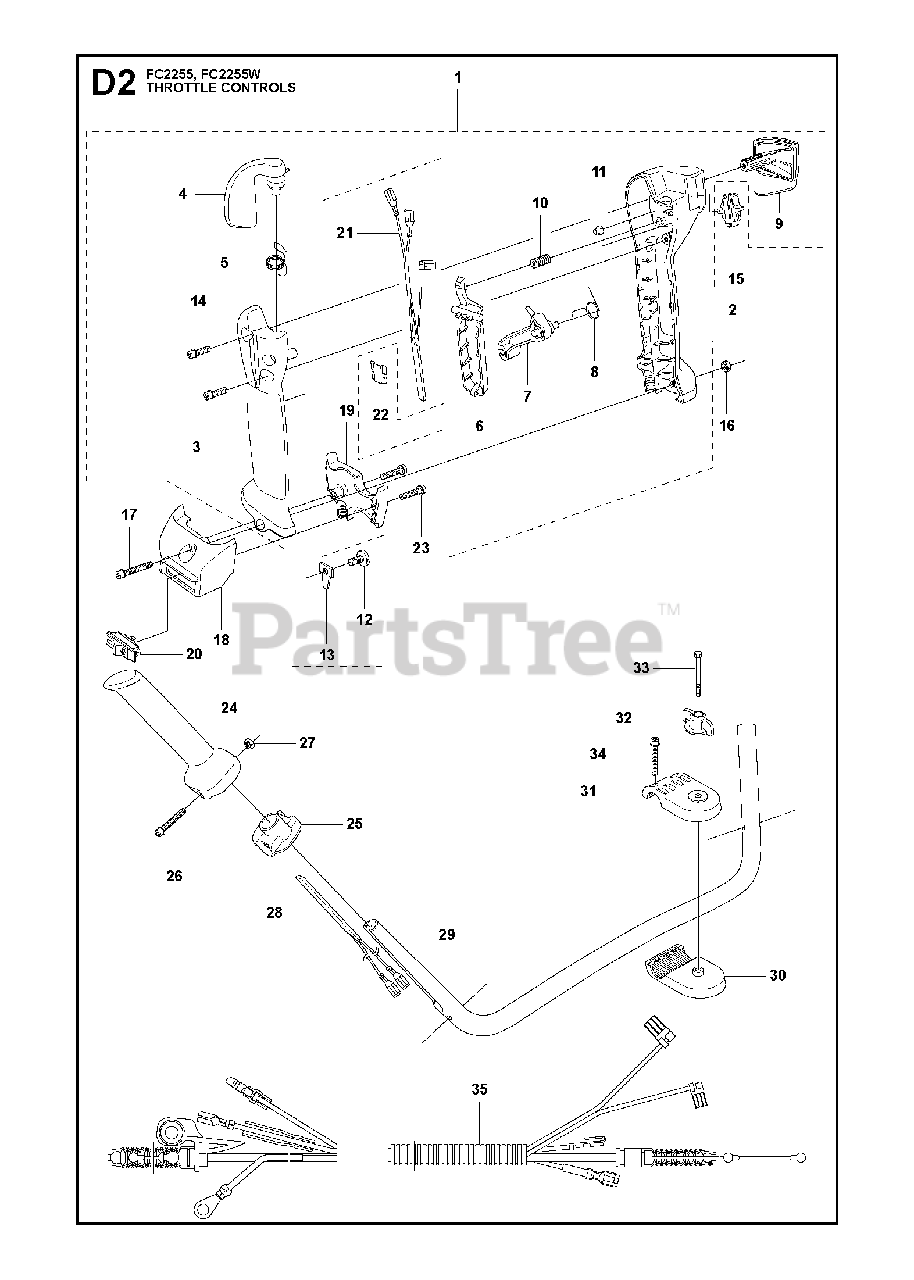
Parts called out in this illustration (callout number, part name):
2	HANDLE HALF RIGHT
5	RP SPRING
7	LEVER
8	SPRING
10	SPRING
11	SLEEVE
12	SCREW
13	HOLDER
14	SCREW
15	STOP BUTTON
16	NUT M6M M5
17	SCREW
20	SWITCH (G)
21	HEATING ELEMENT
23	SCREW
25	HANDLE FASTENER
27	NUT M6M M5
28	HEATING ELEMENT
29	%HANDLE
30	HANDLE BRACKET
31	HANDLE BRACKET
33	SCREW 6X70
35	WIRING
